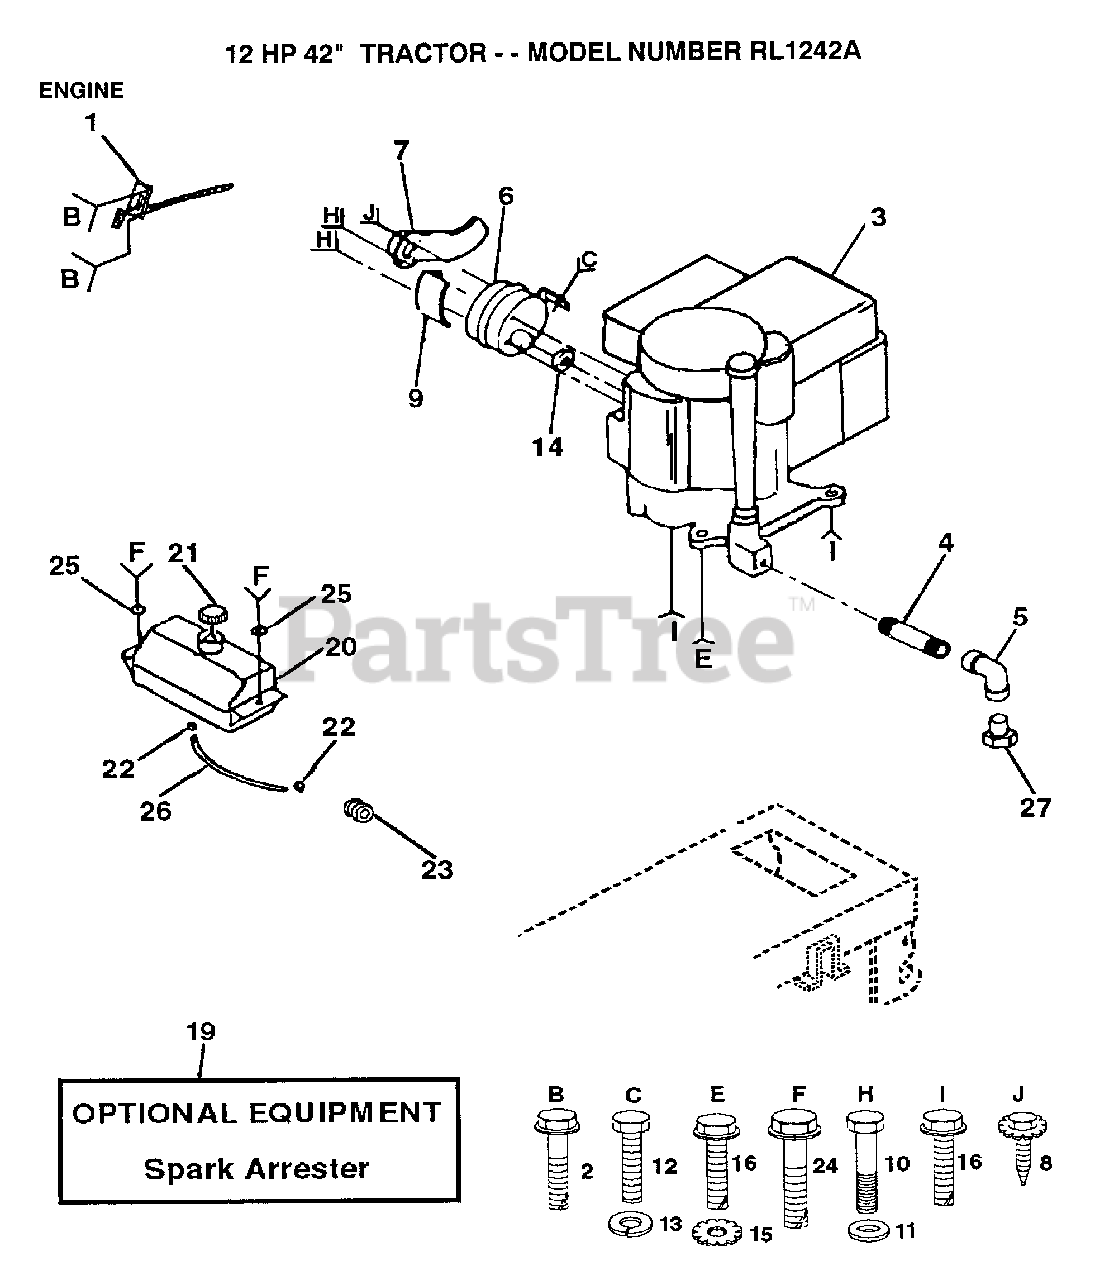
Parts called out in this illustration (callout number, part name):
2	SCREW LT
4	PIPE NIPPLE
5	ELBOW
6	MUFFLER LTV
7	DEFLECTOR MUFFLER
9	SHIELD HEAT LTV
10	"BOLT,HEX"
11	WASHER T
12	BOLT
13	LOCKWASHER
15	SCREW
16	LOCKWASHER
19	SPARK ARREST KIT
20	TANK.FUEL.LT.
22	HOSE CLAMP
24	SCREW HEX CRT
25	WASHER
26	FUEL LINE T
